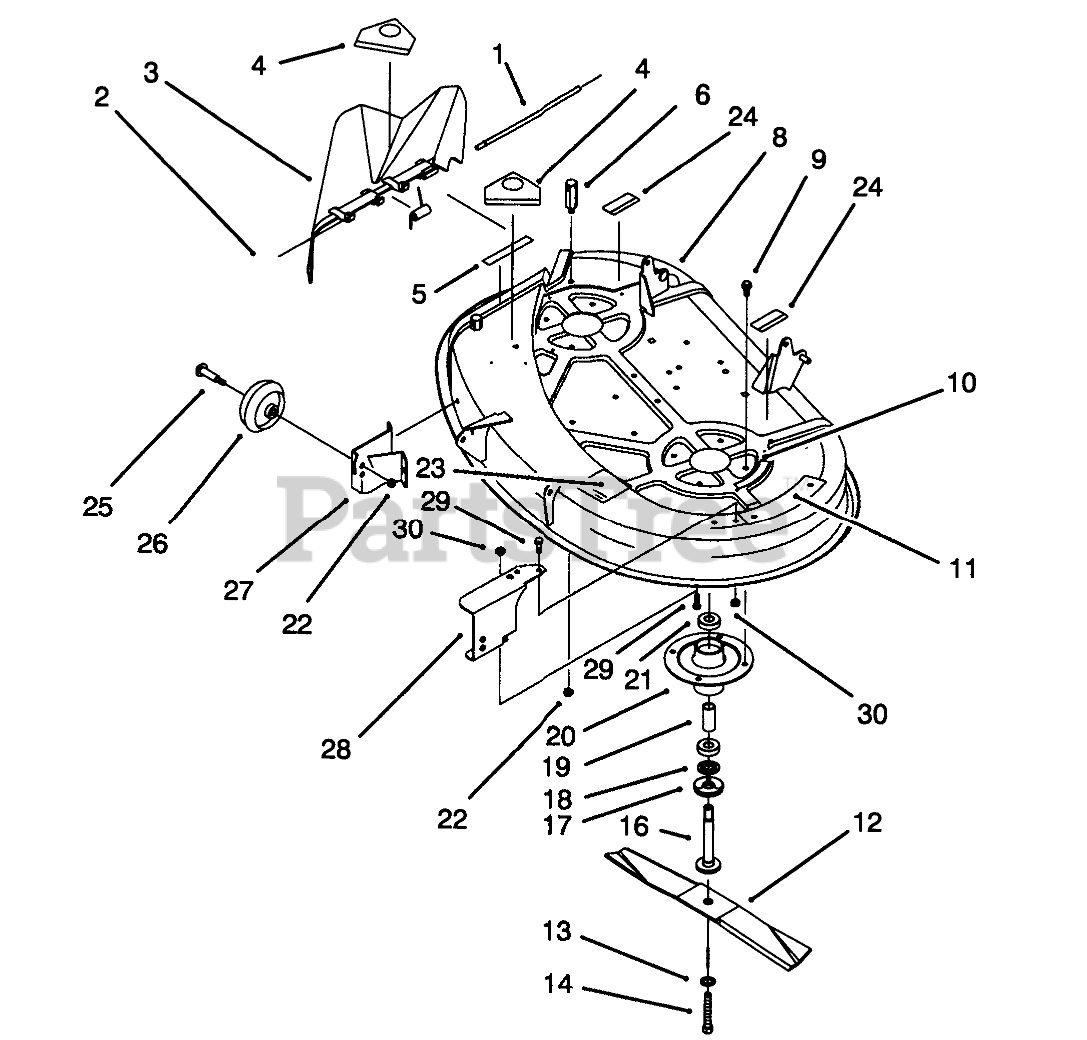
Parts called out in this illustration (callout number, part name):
1	ROD-HINGE DEFLECTOR
2	SPRING
3	Deflector-Deck
4	DECAL-DANGER
5	DECAL-DANGER, DEFLECTOR
6	REAR PIVOT POST (PLTD)
8	Deck-38"
9	SCREW-TAPTITE
10	DECAL-DANGER, SHIELD
11	DECAL-DANGER
12	Blade
13	WASHER-BELLEVILLE
14	SCREW-HH
16	SHAFT-SPINDLE
17	SHIELD-BEARING
18	SPACER
19	SPACER
20	HOUSING-SPINDLE
21	BEARING-BALL
22	NUT-LOCK, NI
23	Decal-Routing
24	DECAL-WARNING
25	SCREW-SHOULDER, HWH
26	WHEEL-GAGE
27	Bracket-R.H.
28	LH WHEEL DECK BRKT
29	SCREW-HH
30	NUT-LOCK, NI
